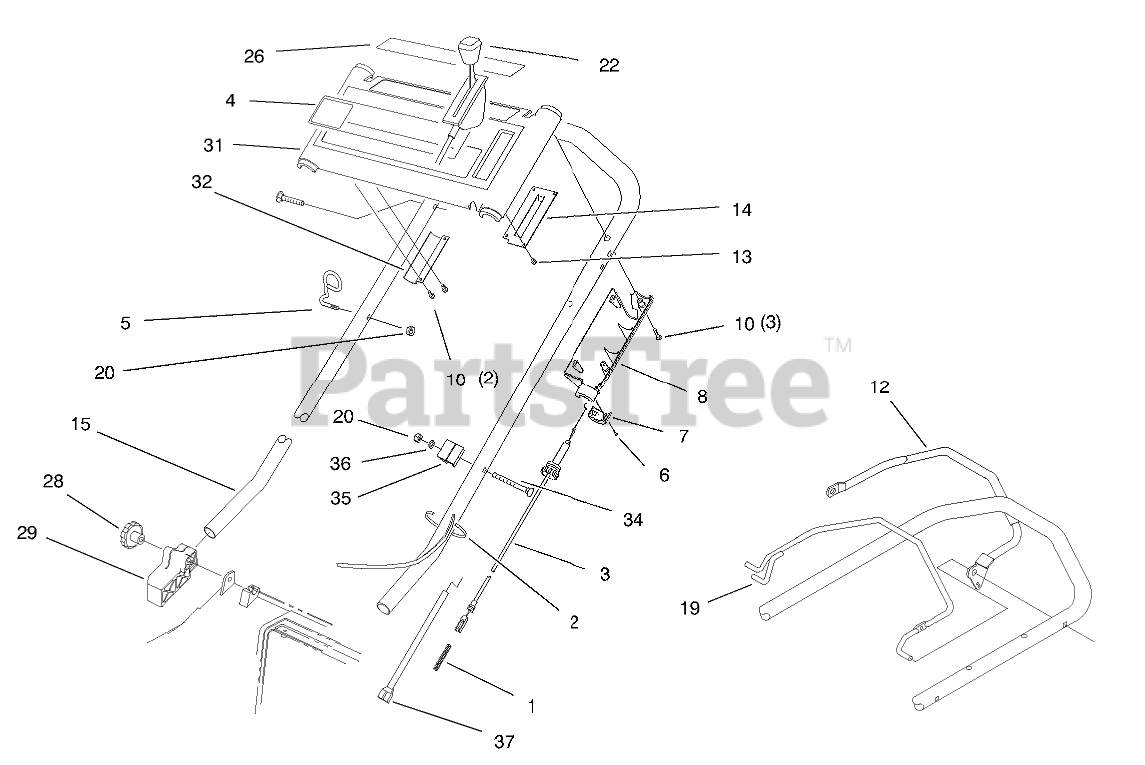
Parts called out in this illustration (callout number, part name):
1	SPRING-COMPRESSION
2	TIE-CABLE
3	CABLE - TRACTION
4	DECAL - PANEL 4-CYCLE
5	GUIDE-ROPE
6	#4-14X.62 PLASTITE SCW
7	LOWER THROTTLE CAP
8	COVER-THROTTLE, LEVER
10	SCREW-PPH, PLASTITE
12	Bail-Traction
13	#6-19X.25 PLASK FORM SC
14	THROTTLE PLATE
15	Handle
19	Bail-Brake
20	NUT-LOCK, NI
22	CONTROL - THROTTLE
26	DECAL - CONTROL PANEL
29	MOUNT-HANDLE, RH
31	Panel-Control (Incl. Ref. # 26)
32	Bracket-Panel
34	SCREW
35	ANCHOR-CABLE, UPPER
36	WASHER-FLAT
37	CABLE - BRAKE
